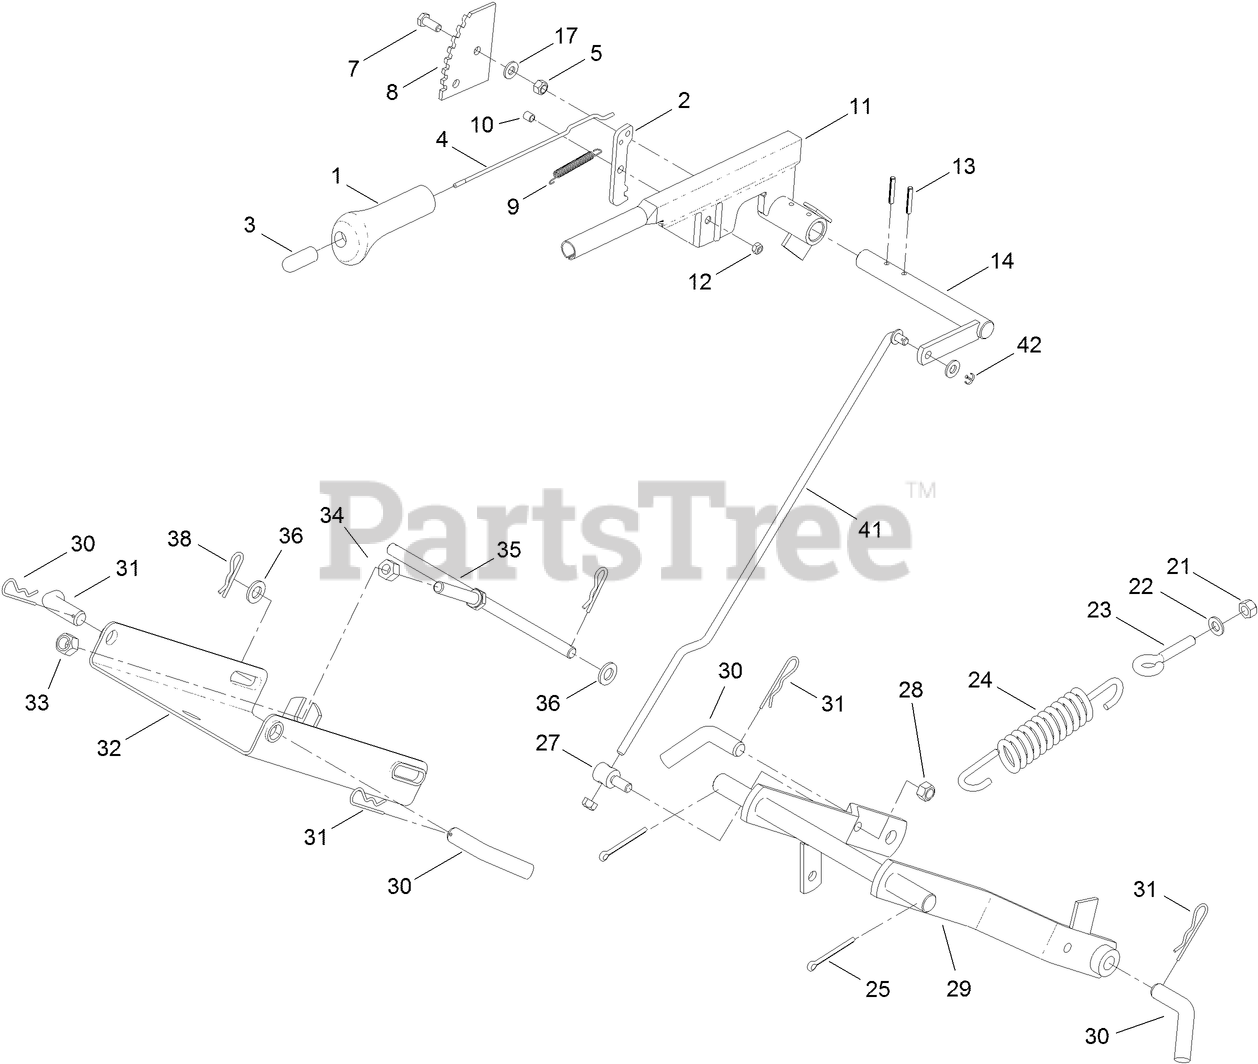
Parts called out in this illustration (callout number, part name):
1	GRIP-HANDLE
2	RATCHET-PLATE, PIVOT
3	BUTTON-PLUNGER
4	ROD-CONNECTION
5	NUT-LOCK, NI
7	SCREW-HH
8	GEAR-SEGMENT, DECK LIFT
9	SPRING
10	BUSHING
11	LEVER-ARM, HEIGHT ADJ.
12	NUT-LOCK
13	PIN-SPRING
14	SHAFT-LIFT, DECK
17	WASHER-PLAIN
21	NUT-LOCK, NI
22	WASHER-FLAT
23	BOLT-EYE
24	SPRING-LIFT
25	PIVOT ARM ASM
27	PIN-LIFTING
28	NUT-LOCK, NI
29	PIN-COTTER
30	PIN-BENT
31	PIN-HAIR
32	SUSPENSION-MOWER DECK, FRONT
33	NUT-HEX
34	NUT-HEX
36	WASHER-FLAT
38	PIN-HAIR
41	ROD-HEIGHT, ADJ.
42	PIN-COTTER
